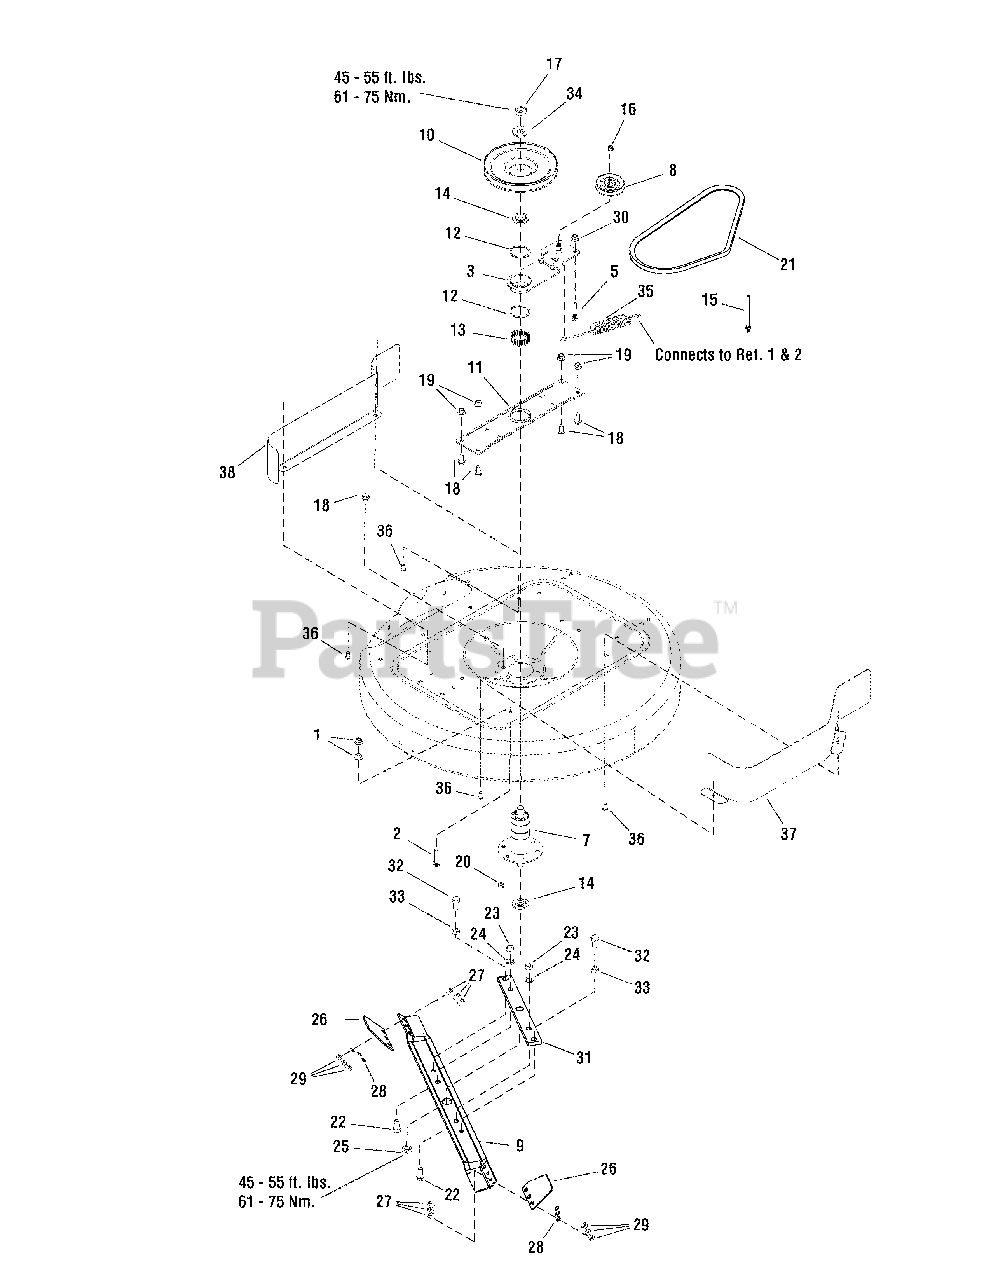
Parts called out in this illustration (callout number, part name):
1	NUT, 5/16-18
2	BOLT, 5/16-18 x 2.0
3	BLADE, Idler Bracket
5	BELT GUIDE
7	SPINDLE ASSY
8	IDLER PULLEY
9	BLADE, 33"
10	PULLEY, 33" Input
11	BRACE, Spindle
12	RING, Retaining
13	TOLERANCE RING
14	WASHER, Spindle
15	BELT GUIDE, LONG
16	NUT, Flange 3/8-16
17	NUT, Hex, Jam, 3/4F GR8
18	BOLT, Hex 3/8-16 x 0.75
19	NUT, Hex Flange, 3/8-16
20	NUT, Centerlock, 3/8-16
21	BELT, 33" Blade Drive
22	BOLT, 1/2-20 x 1.25
23	NUT, Hex Jam, 1/2-20
24	WASHER, 1/2" Internal Tooth Lock
25	NUT, 5/8-18 Hex Center Lock Jam
26	33" AIR LIFT
27	SCREW, Oval Head, 5/16 - 24 x 21/32
28	WASHER, 5/16" Internal Tooth Lock
29	NUT, Hex, 5/16 - 24
30	NUT, Hex Flange 5/16-18
31	HOLDER, Blade
32	SCREW, 1/2-20 x 1-1/4" Hex Head Cap, GR5
33	NUT, 1/2-20 Hex
34	WASHER 25/32 x 1.5 x .132
35	SPRING, Extension PTO
36	BOLT, Carriage, 3/8-16 x 5/8
37	GUARD, LH
38	GUARD, RH
